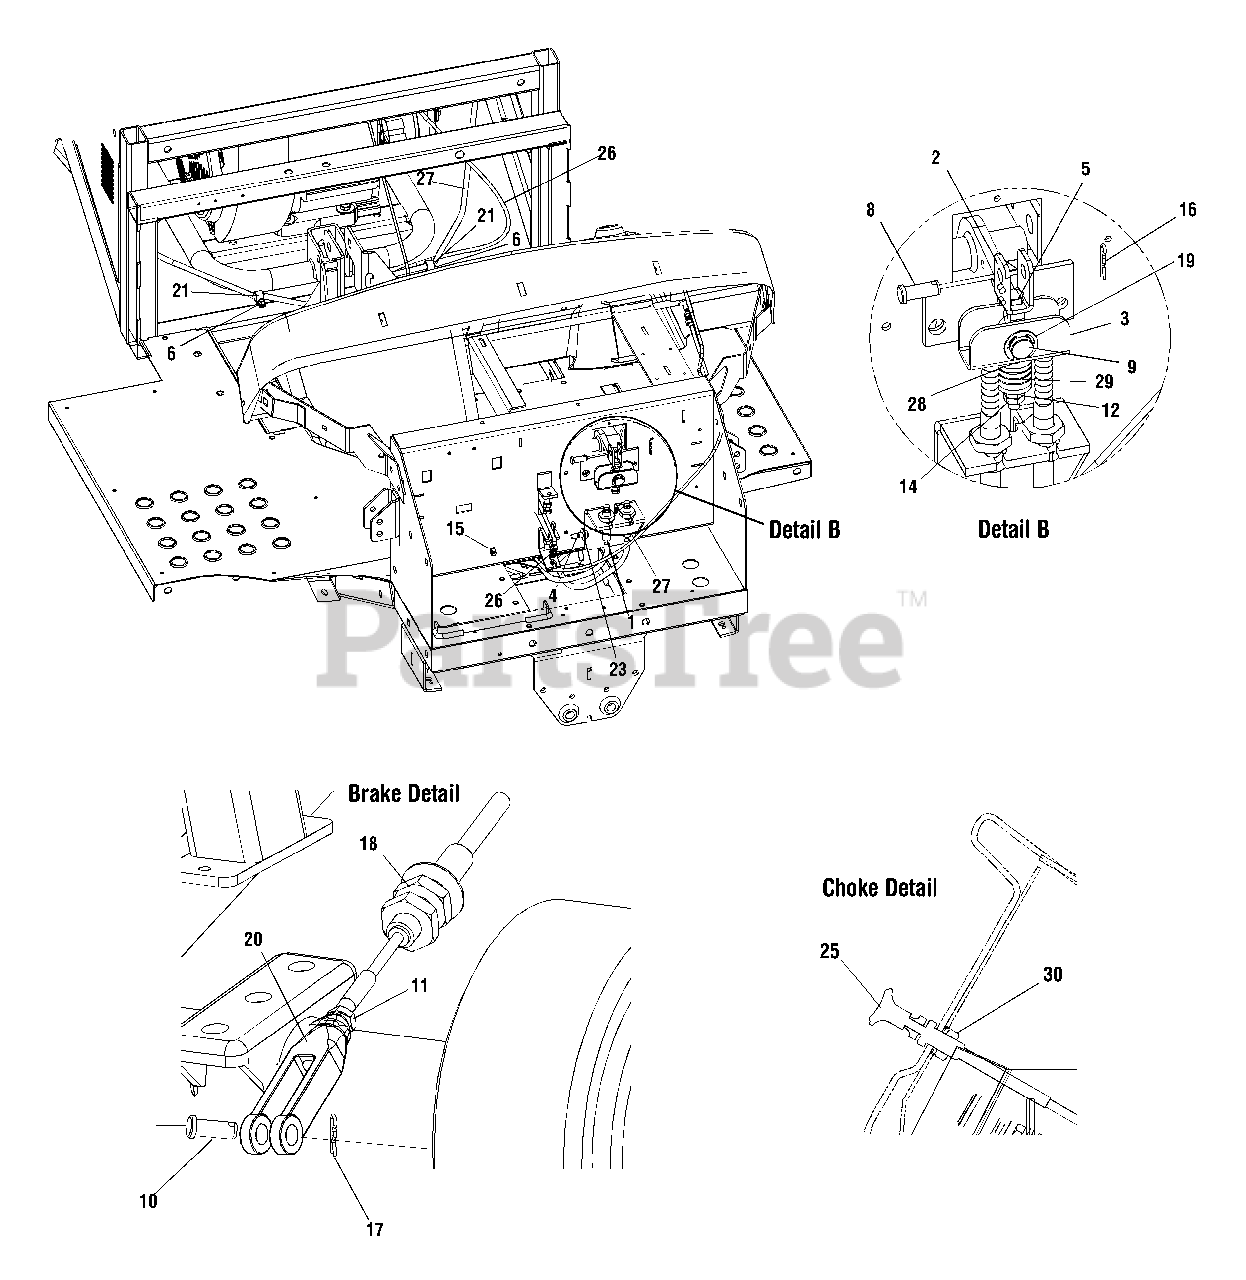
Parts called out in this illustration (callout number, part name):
1	Cable, Control, Brake
2	Mount,Cable
3	Bracket, Equalizer
4	Screw, Shoulder, .375 x .375
5	Screw, 5/16-18 x 3.5
6	Screw, Self-Tapping
8	Pin, Clevis 375 x.969
9	Pin, Clevis.625 OD x 1.37
10	Pin, Clevis.312 OD x 1.0
11	Nut, Jam 5/16-24
12	Nut, Hex 5/16-18
14	Nut, Jam 5/16-18
15	Hexlock Nut, 5/16-18
16	Pin, Cotter, .072 x 1.13
17	Pin, Cotter 3-32 x.750
18	E-Ring for.500 Dia Shaft
19	E-Ring.625 Shaft
20	Yoke, 5/16-24
23	Washer, .349 x .879 x .063
25	Cable, Control, Choke
26	Cable, Control, Throttle
27	Cable, Control, Brake
28	Spacer,.466 OD x.443
29	Washer, Belleville,.937 x.328 x.07
30	Nut, 3/8-16 T-Lock
